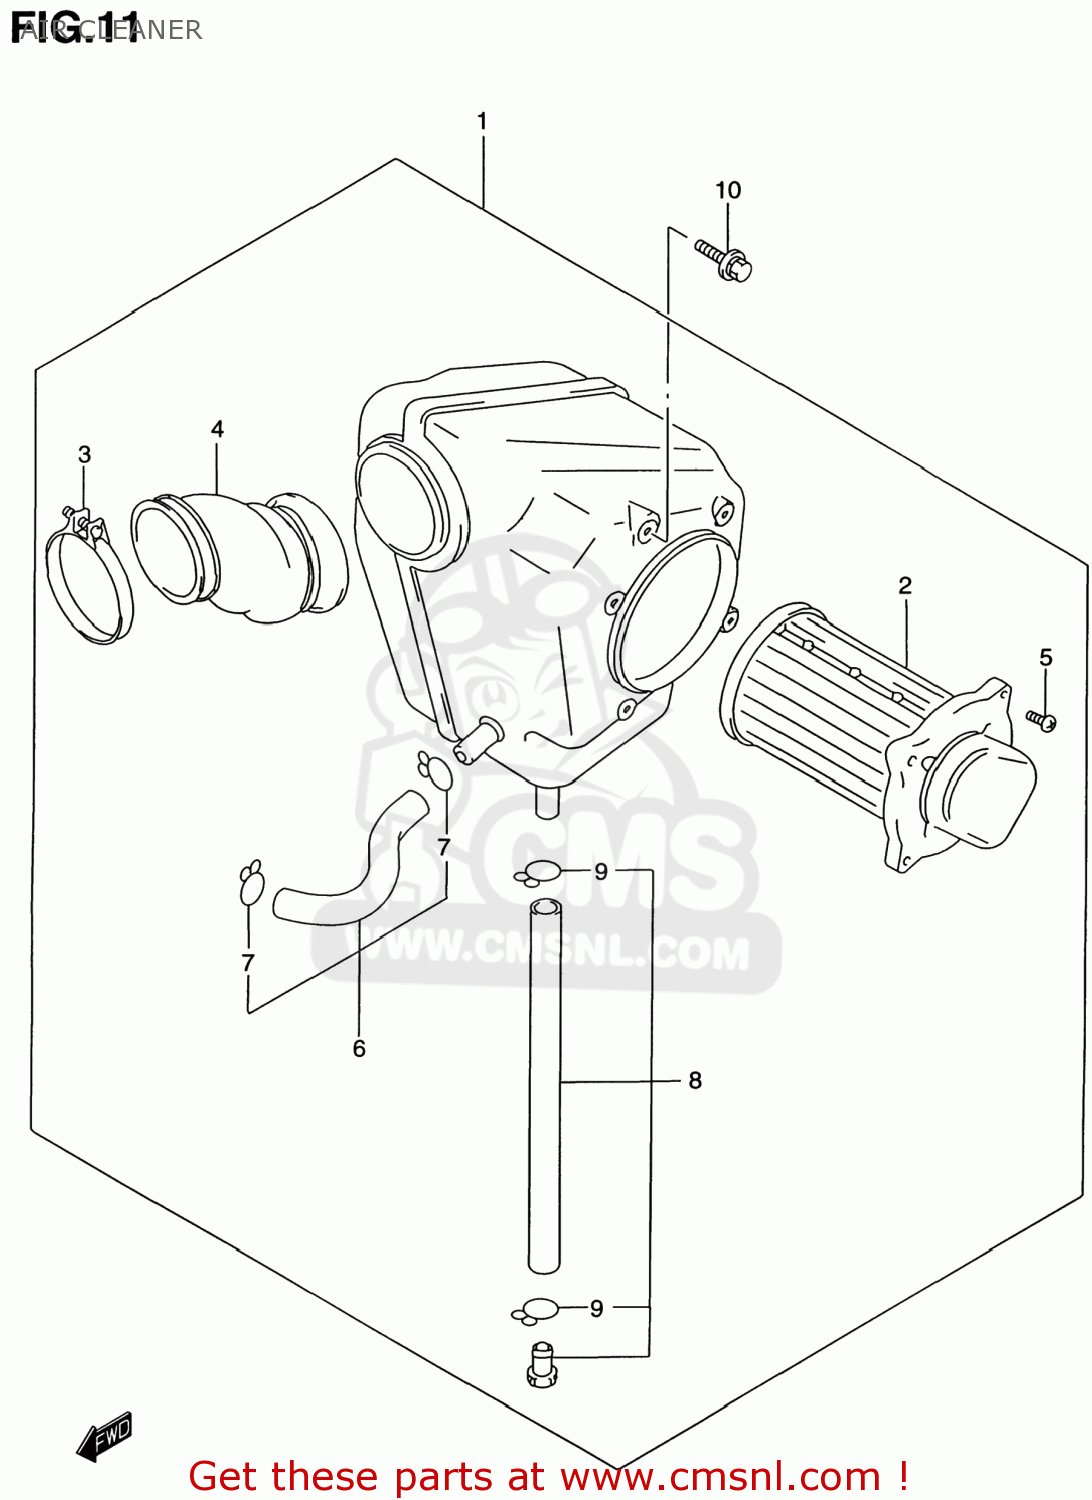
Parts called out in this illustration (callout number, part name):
1	CLEANER ASSY,AIR
2	FILTER,AIR CLEANER
3	CLAMP
4	TUBE,OUTLET
5	SCREW
6	TUBE,BREATHER
7	CLIP
8	TUBE,DRAIN
9	CLIP
10	BOLT
